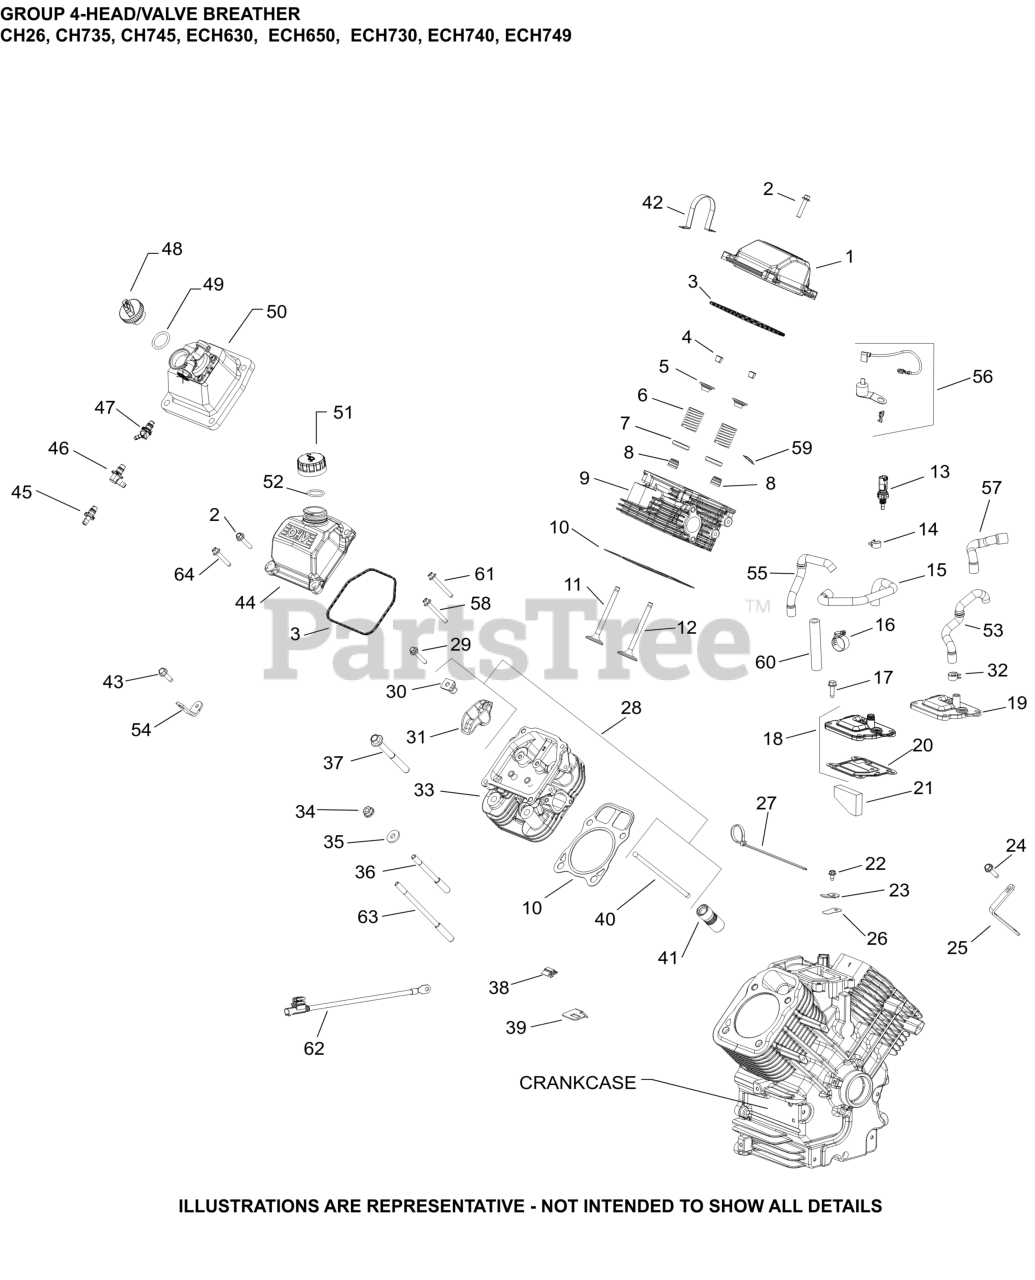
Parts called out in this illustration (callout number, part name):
1	KIT, VALVE COVER-PLAIN (PLASTIC)
3	O-RING (YELLOW), VALVE CO
4	KIT, RETAINER
5	CAP, VALVE SPRING
6	SPRING, VALVE
7	RETAINER, SPRING
8	SEAL, VALVE BAND
9	KIT, CYLINDER HEAD (#1)-(#2481803S)
10	KIT, GASKET CYLINDER HEAD
11	VALVE, EXHAUST
11	VALVE, EXHAUST (.25)
12	VALVE, INTAKE (STD)
12	VALVE, INTAKE (.25)-(#DSC)
17	SCREW, THREAD FORMING
19	COVER, BREATHER
20	GASKET, BREATHER
21	FILTER, BREATHER
22	SCREW, FLG THD FRM M5X.8X10
23	RETAINER, REED
26	REED, BREATHER
28	KIT, VALVE TRAIN
30	PIVOT, ROCKER ARM
31	ARM, ROCKER
32	SPRING CLAMP, HOSE
33	KIT, CYLINDER HEAD (#2)-(#2481804S)
34	NUT, FLG M8X1.25
35	WASHER, FLAT 8.6 MM
36	STUD, M8X1.25
38	CLIP, O2 SENSOR
40	ROD, PUSH
41	LIFTER, VALVE HYDRAULIC-USE 25 351 11-S
44	KIT, VALVE COVER-OIL FILL
51	KIT, OIL FILL CAP (YELLOW)
52	O-RING, DIPSTICK
57	HOSE, BREATHER (ETB HORIZONTAL)
59	RETAINER, VALVE GUIDE (KM)
61	SCREW, HEX FLANGE
62	LEAD, SENSOR TEMPERATURE
64	SCREW, HEX FLANGE (M6 X 31.625 DOG PT)
